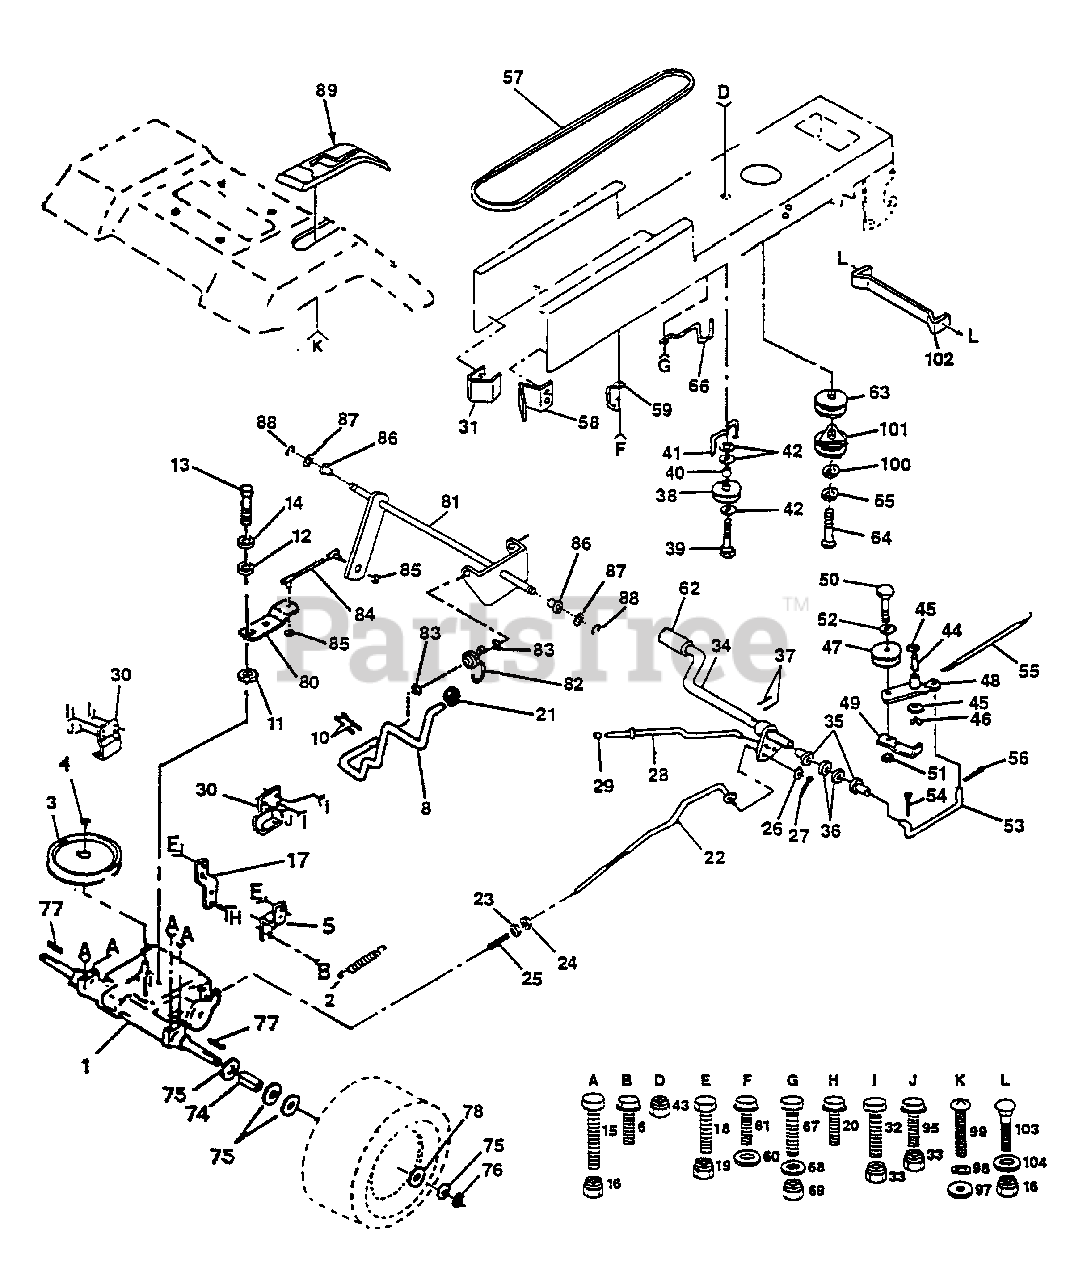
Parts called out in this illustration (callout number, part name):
2	Spring Return Brake T/a Zinc
3	Pulley Transaxle 20" tires
4	Ring Retainer # 5100-62
5	Strap Torque 30 Degrees
6	Screw Thdrol 5/16-18 X 3/4 TYT
8	Rod Shifter
10	Pin Cotter 1/8 X 1 Cad
11	Washer Plate Shf 388 Sq Hole
12	Washer 15/32 X 3/4 X 16 Ga
13	Bolt Fin Hex 1/4-28unf x 3/4 Gr8
14	Washer Lock Hvy Helical 1/4
15	Bolt Fin Hex 5/16-18unc x 2 1/2
16	Nut Crown Lock 5/16-18
17	Strap Torque LT
18	Bolt Fin Hex 3/8-16unc X 3/4
19	Nut Crownlock 3/8-16 Unc
20	Screw Thdrol 5/16-18 X 3/4 TYT
21	Knob Duckhead 3/8-16unc Blk
22	Rod Brake Blk Zinc 27 326
23	Nut Lock Hex W/wsh 3/8-16unc
24	Nut Hex Jam 3/8-16 Unc
25	Spring Rod Brake 2 00 Zinc
26	Washer 13/32 X 13/16 X 16 Ga
27	Pin Cotter 1/8 X 3/4 Cad
28	Rod Brake Parking 14 500
29	Cap Brake Parking Black
30	Bracket Mtg Transaxle
31	Keeper Belt LH LT 14 Ga
32	Bolt Hex Hd 5/16-18unc X 3/4
33	Nut Crown Lock 5/16-18
34	Shaft Asm Pedal Foot 1 930
35	Bearing Nylon Blk 629 Id
36	Washer 21/32 X 1 X 16 Ga
37	Pin Roll 3/16 X 1"
38	Pulley Idler Flat
39	Bolt Fin Hex 3/8-16unc X 2-3/4
40	Spacer Split 395 X 59 Bzp
41	Keeper Belt Retainer
42	Washer 13/32 X 13/16 X 12 Ga
43	Nut Crowniock 3/8-16 Unc
44	Bearing Nyl 503 X 628 X 1 25
45	Washer Hardened
46	Ring Klip #t5304-50
47	Pulley Idler V Groove Plastic
48	Bellcrank Asm Clutch
49	Retainer Belt Style Spring
50	Bolt Hex Hd 3/8-16unc X 1-1/2
51	Nut Crowniock 3/8-16 Unc
52	Washer 13/32 X 13/16 X 16 Ga
53	Link Clutch 7 66
54	Pin Cotter 1/8 X 3/4 Cad
55	Spring Return Clutch 6 75
56	Pin Cotter 1/8 X 3/4 Cad
57	V-Belt Ground Drive 95 25 42"
58	Keeper Belt RH LT Pnt/zinc 16g
59	Keeper Belt Chassis Span Ctr
60	Washer 13/32 X 13/16 X 12 Ga
61	Screw Thdrol 3/8-16x3/4 Ty-tt.
62	Cover Pedal Premuim
63	Engine Pulley LT/YT
64	Bolt, Hex 7/16-20 x 4-1/4
65	Washer Lock Hvy Hlcl Spr 7/16
66	Keeper Belt Engine LH LT
67	Bolt Fin Hex 3/8-16unc X 1
68	Washer 13/32 X 13/16 X 12 Ga
69	Nut Crownlock 3/8-16 Unc
74	Spacer Split
75	Washer 25/32 X 1 1/4 X 16 Ga
76	E-ring #5133-75
77	Key Square 2 0 X 184511865
78	Washer 25/32 X 1-5/8 X 16 Ga
80	Arm Shift Transaxle
81	Shaft Asm Cross 20"t 42" deck
82	Spring Torsion T/a
83	Washer 17/32 X 3/4 X 16 Ga
84	Rod Tie Shift Adj Ball
85	Nut Nylock 1/4-28
86	Bushing Rod Strg 629/632 Id
87	Washer 21/32 X 1-1/4 X 16 Ga
88	Ring Klip #5304-62
89	Console Shift 6sp W/ign LT
95	Screw Thdrol 3/8-16 x 314
97	Washer 3/16 X 7/16 X 18 Ga
98	Washer Lock #8
99	Screw #8x1/2
100	Washer 1-1/2 OD X 15/32 ID X .250
101	Clutch Electric
102	Bracket Asm. Clutch
103	Bolt, Carriage 5/16-18 x 3/4
104	Washer 11/32 x 5/8 x 12 Ga.
